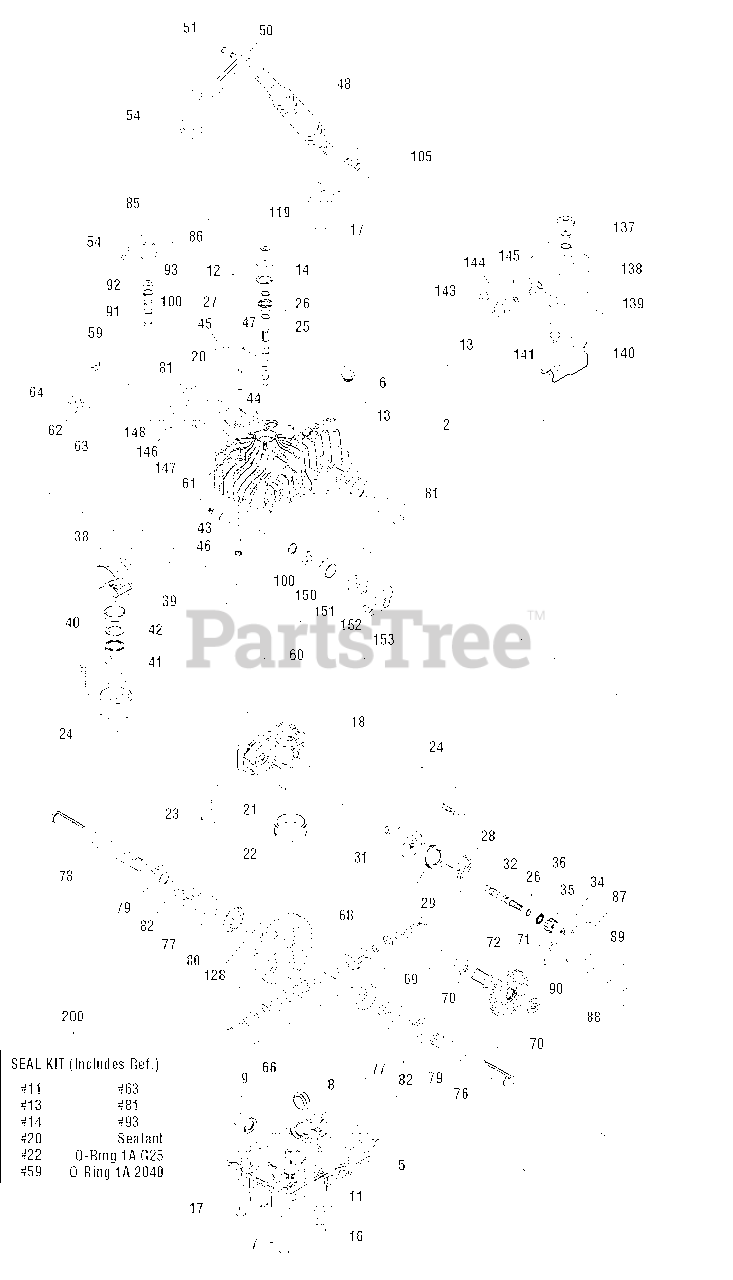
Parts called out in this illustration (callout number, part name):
2	*HOUSING, Upper
5	*HOUSING, Lower
7	BOLT, 8 x 75
8	FILTER (25)
11	WASHER, SEAL
14	SEAL
16	BOLT 10 x 12
17	SCREW, TAPPING
18	*CASE, Center
20	O-RING, 1A P10A
21	PIN 3 x 9.8
22	FILTER (25)
23	BOLT, 10 x 65
24	CYLINDER BLOCK
25	SHAFT, PUMP
27	BEARING 6202UC3
28	*HOUSING
29	BEARING, THRUST
31	WASHER 12 x 24 x 1
32	*SHAFT, Motor
34	*E-RING, Motor
35	*GEAR, Motor
36	BEARING, 6302UC3
38	THRUST METAL
39	*PLATE, Swash
40	BEARING K81106
41	*THRUST PLATE A
42	THRUST PLATE B
44	*SHAFT (BYPASS)
45	LEVER, BYPASS
47	PIN 3.0A x 20
48	SHOCK ABSORBER
50	*LEVER, Control
54	PIN 6.0A x 4.0
59	SEAL TC162606
61	FULCRUM ECCENTRICITY
66	*DIFFERENTIAL GEAR KIT
68	GEAR, FINAL
69	*SHAFT, Final Pinion
70	WASHER, 15 x 32 x 3.2
71	GEAR, REDUCTION
72	PINION, FINAL
78	SHAFT, AXLE RH #1
79	*BUSHING
80	COLLAR, 25.4
81	SEAL S25.4 x 42 x 8
82	THRUST WASHER
86	SPRING, BRAKE
87	DISC, Brake
88	*SHOE, Brake
90	ACTUATOR, BRAKE
92	WASHER, 16 x 23 x 1.6
93	PACKING
119	RING E15
137	VALVE, VENT 15
138	TANK, RESERVOIR
140	*BRACKET, Tank
141	SCREW, TAPPING
143	BOLT, 8 x 20
144	*FITTING
146	PIN 3.5 x 25
147	PIN 6.0A x 25
148	*SHAFT, Control
151	*COLLAR, Control
152	*SPRING, Torsion
153	*ARM, Control
201	*KIT, Repair
